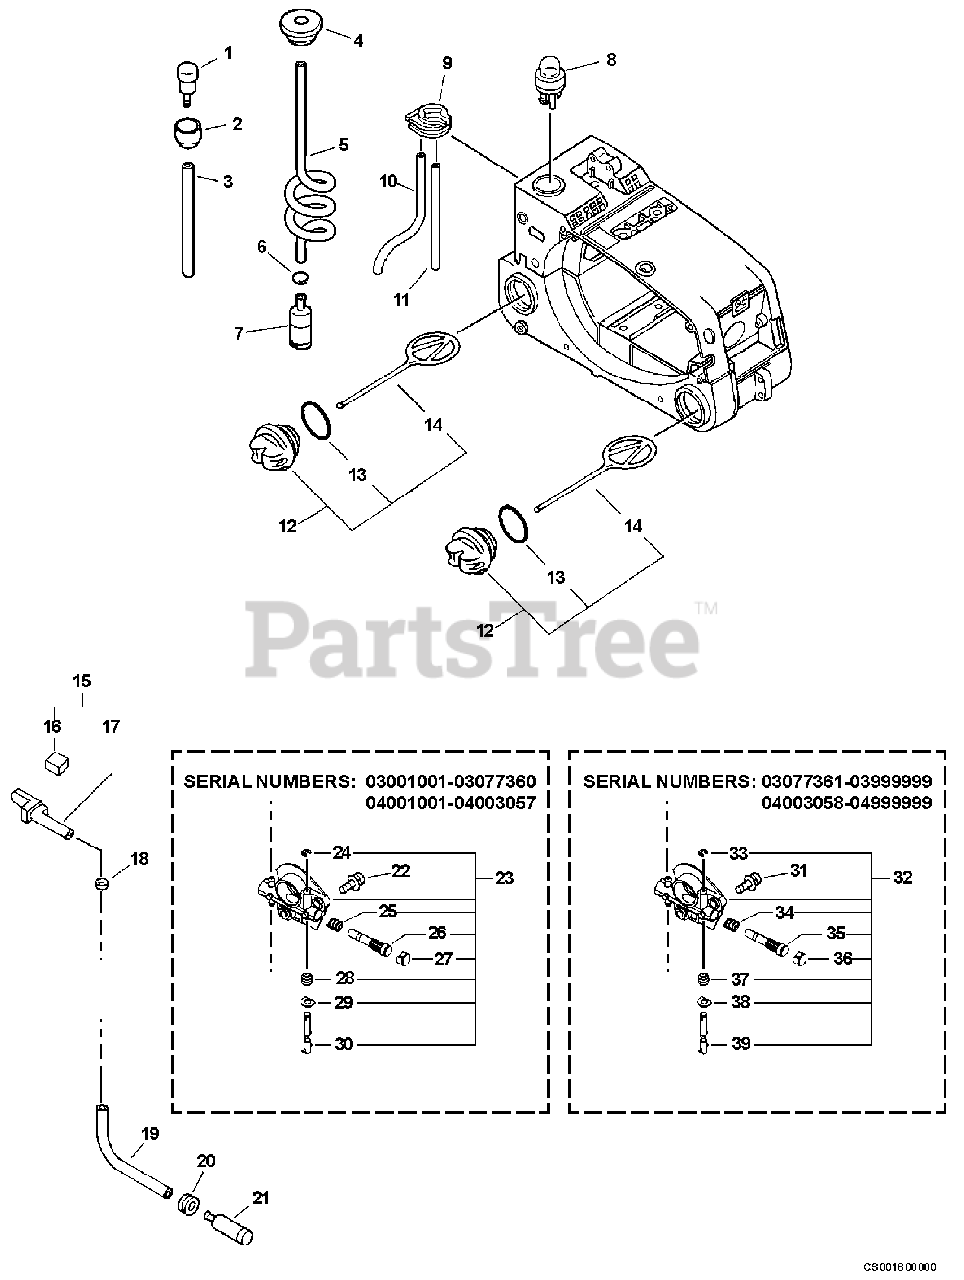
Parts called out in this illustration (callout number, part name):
1	VENT ASSY
2	HOLDER, VENT
3	PIPE, FUEL 3×5×150 BLACK
4	GROMMET, FUEL
5	PIPE, FUEL 3×6×160
6	CLIP Ø6.5 MM
7	FILTER, FUEL
8	BULB, PURGE
9	BRACKET, BULB
10	PIPE, FUEL 2×4×42 CLEAR
11	PIPE, FUEL 3x-5x-70 BLACK
12	CAP ASSY, OIL
13	O-RING 25
14	CONNECTOR, CAP L= 60 MM
15	PIPE KIT, OIL
16	PAD, FOAM
17	PIPE, OIL OUTLET
18	CLIP Ø6.5 MM
19	PIPE 3×6×115 BLACK
20	GROMMET
21	FILTER, OIL
22	SCREW 5×12
23	AUTO-OILER ASSY
26	PLUNGER ASSY
27	CAP, OIL PUMP
30	ADJUSTER, OILER
31	SCREW 5×12
32	AUTO-OILER ASSY
35	PLUNGER ASSY
36	CAP, PLUNGER
39	ADJUSTER, OILER
